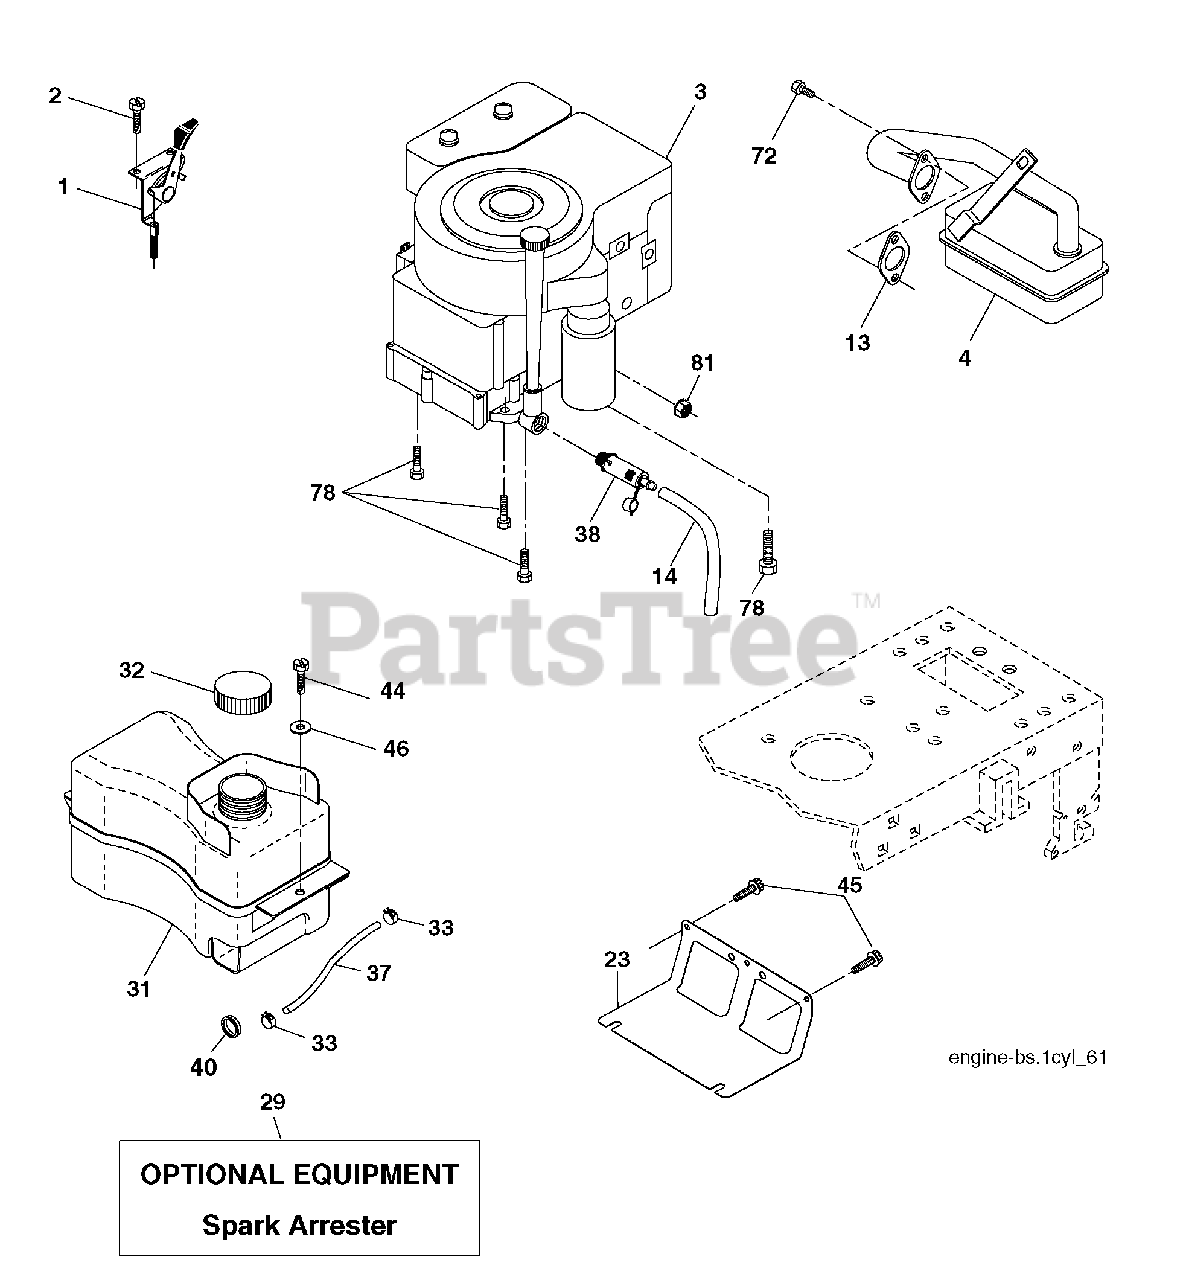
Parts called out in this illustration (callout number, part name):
1	Control Th/ch Flag
2	Screw Hex Thd Cut 1/4-20 x 1/2
4	Muffler Exhaust B&S
13	Gasket Eng 1 313 Id Tin Plated
14	Tube Drain Oil Easy
23	Shield BRN/DBR Guard
29	Kit Spark Arrester (Flat Scrn)
31	Tank Fuel Front
32	Cap Asm Fuel
33	Clamp Hose
37	Line Fuel 20"
38	Plug Drain Oil
40	Bushing Snap Nyl Blk Fuel Line
44	Screw Thdrol 1/4-20 x 3/4
45	Screw Hex Wsh Thdrol 3/8-16
46	Washer 9/32 x 7/8 x 16 Ga.
72	Screw Socket Head 5/16-18 x 3/4
78	Screw 3/8-16 x 1-1/4
81	Nut Keps Hex 1/4-20 unc
